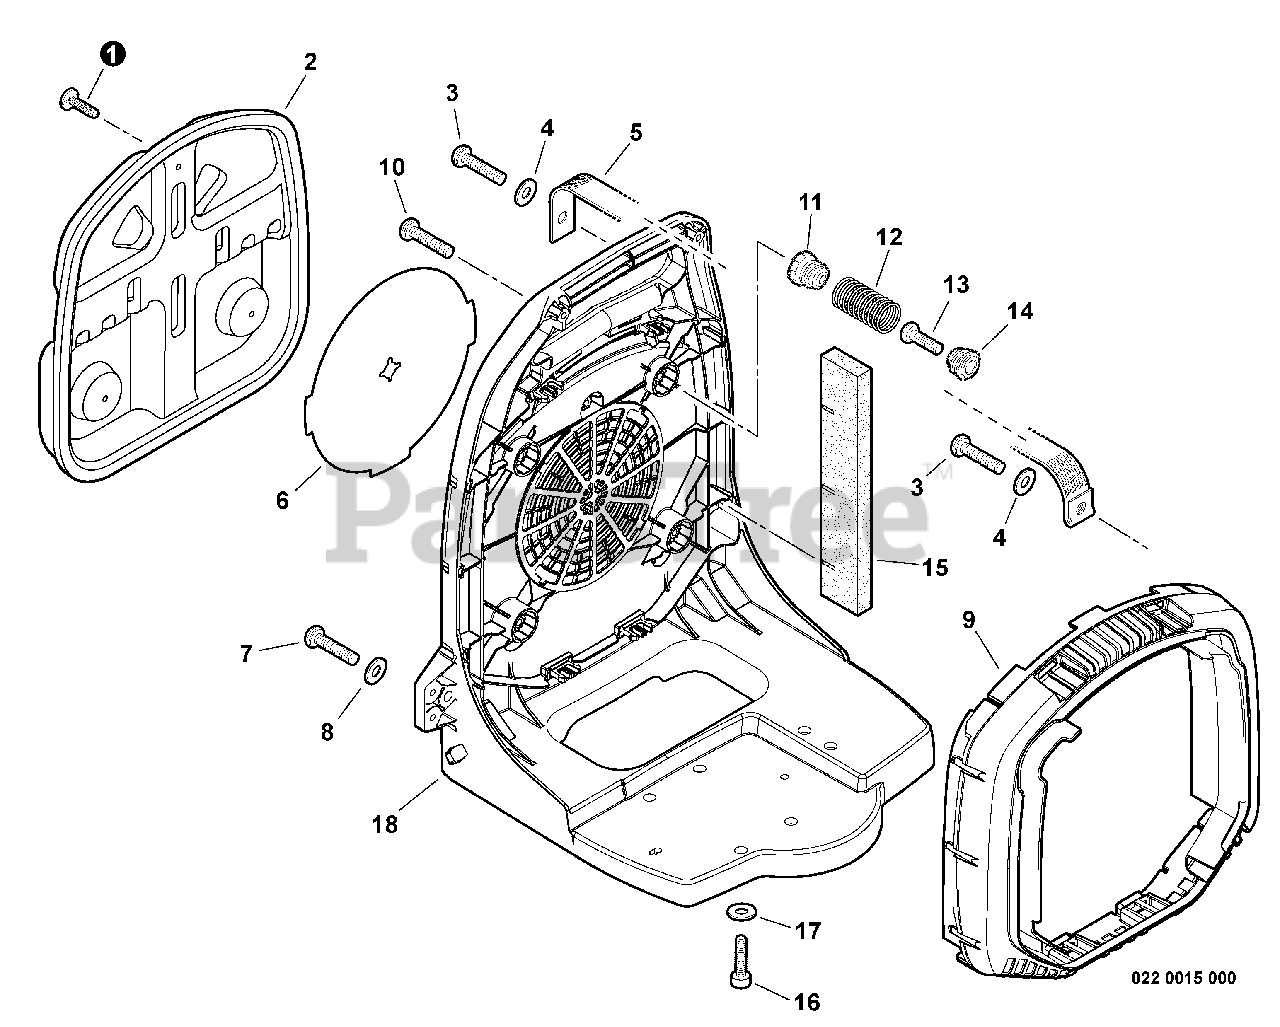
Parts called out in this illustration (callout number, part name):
2	CUSHION, BACKPACK
3	SCREW - 5X20
4	WASHER - 5
5	STRAP, SAFETY
6	INSERT, COLD WEATHER
7	SCREW - 5X20
8	WASHER - 5
9	GUARD, DEBRIS
10	SCREW - 5X20
11	HOLDER, SPRING
13	SCREW - 5X16
14	HOLDER, SPRING
15	PAD, FOAM
16	SCREW - 5X25
17	WASHER - 5
18	FRAME, BACKPACK
